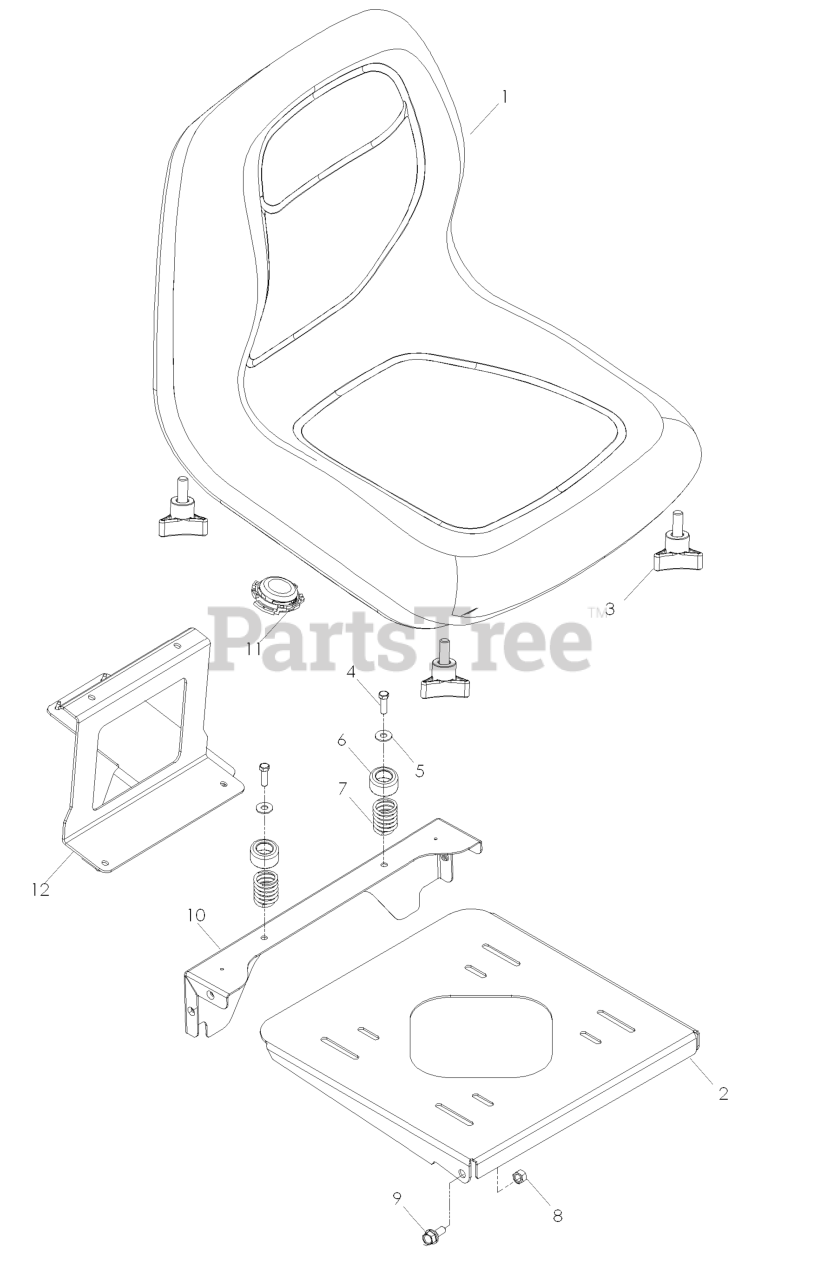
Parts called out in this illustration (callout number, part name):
1	SEAT.HIGHBACK.GRAY
1	SEAT.XH150.LOWBACK.GREY.ZTR
2	SEAT MOUNT, BLACK
3	KNOB W/STUD
4	BOLT, SHOULDER
5	WASHER 3/8 FLAT
6	CAP, SPRING COVER
7	SPRING, SEAT
8	NUT 5/16 NYLOC
9	HCS 3/8C X 1 1/4 GR5
10	REAR SEAT SUPPORT
11	SWITCH, SEAT N/C
12	BRACKET, FRONT SUPPORT Model 968999281 only
